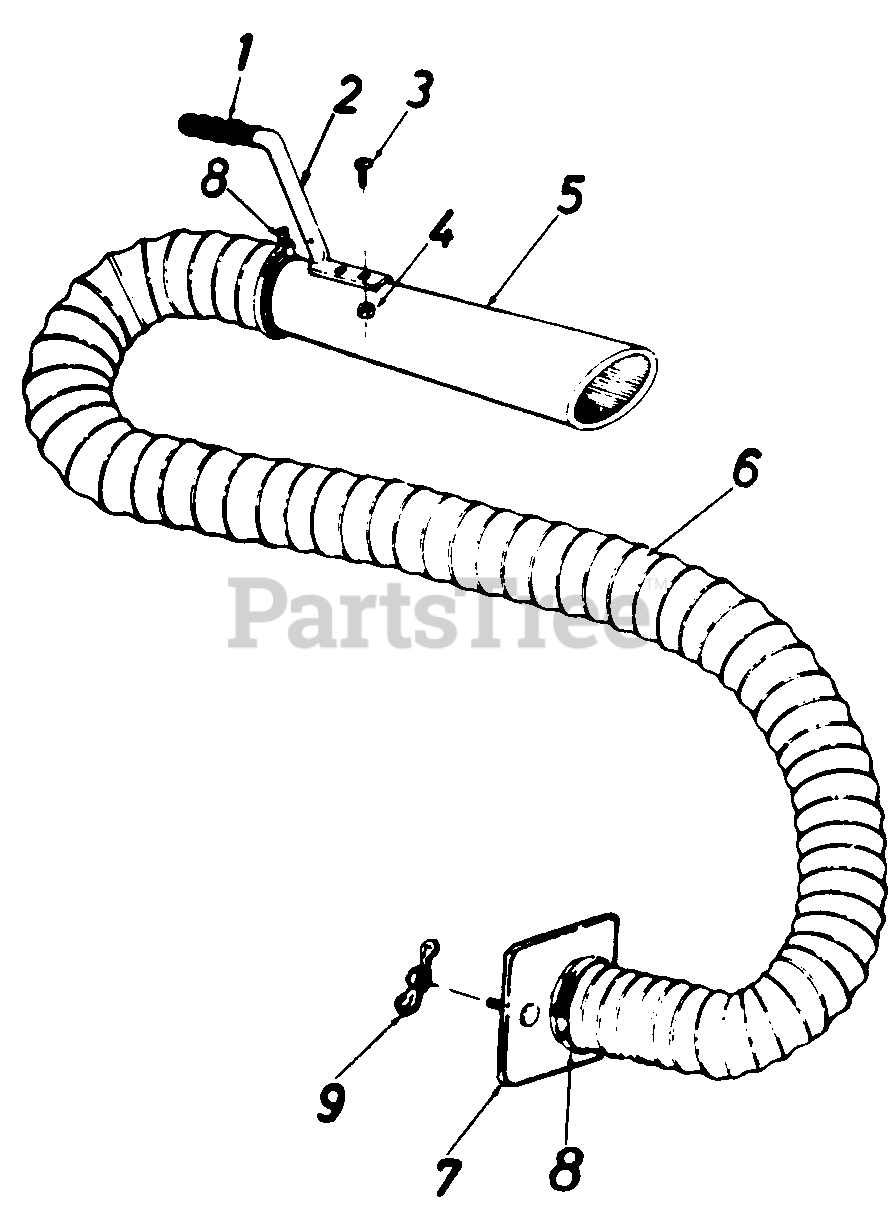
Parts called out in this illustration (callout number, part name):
1	Handle Grip
2	Handle
3	Truss Sems Scr. 10-24 x 1/2" Lg.*
4	Hex Nut 10-2 Thd.
5	Hose Nozzle
6	Flexible Hose 4" Dia. x 10' Lg.
7	Hose Adapter Plate
8	Hose Clamp - For 4" Dia. Hose
9	Wing Nut 1/4-2 Thd.
